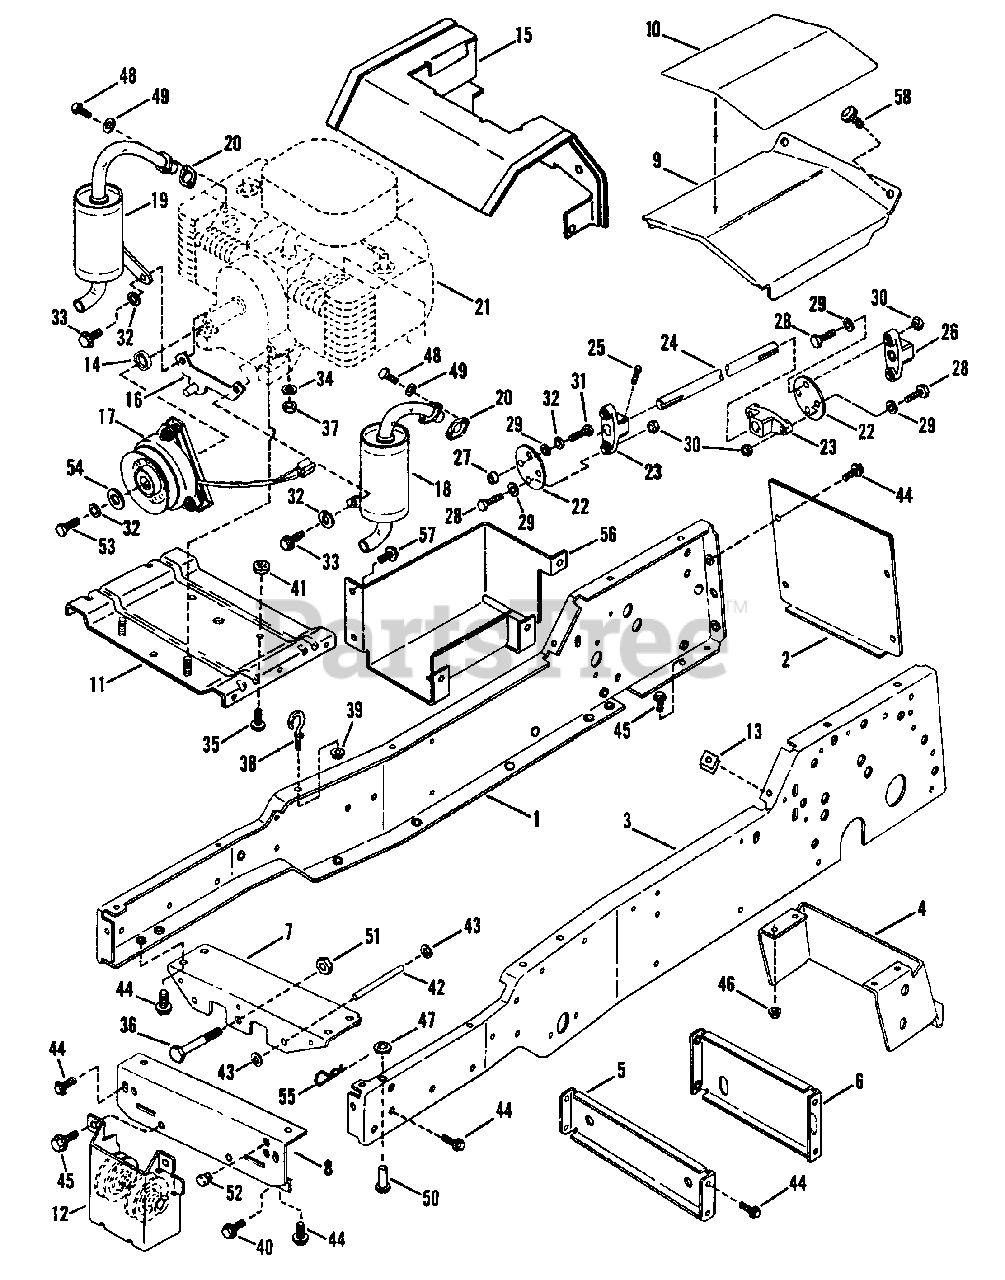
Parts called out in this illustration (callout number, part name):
1	CHANNEL, Right Hand Frame
2	PLATE, Rear Cover
3	CHANNEL, Left Hand Frame
4	DRAWBAR
5	BRACE, Forward
6	BRACE, Rear Cross
7	CHANNEL, Front Axle Support
8	PLATE, Front Frame
9	COVER, Console
10	DECAL, Console Cover
11	BASE, Engine
12	ASSEMBLY, Mule Drive
13	U-NUT, 1/4-20 x 3/4"
14	SPACER, 1" x 1 3/8 x .30" (PM)
15	ASSEMBLY, Heat Shield
16	BRACKET, Clutch Retainer
17	KIT, Electric Clutch
18	MUFFLER, LT 12 & LT 16 Engine - B&S
19	MUFFLER, LT 12 & LT 16 Engine - B&S
20	GASKET, Exhaust
21	ENGINE, Briggs Model 402437-1206-01, 16 HP
22	DISC, Flex Coupling
23	HUB, Flex Coupling
24	SHAFT, Drive
25	SET-SCREW, 5/16-18 x 1/2" Square Head
26	HUB, Flexible Coupling (Threaded center)
27	SPACER, Flexible Coupling
28	SCREW, 3/8-16 x 1", Hex Head Cap, Grade 2
29	WASHER, 3/8" Flat
30	NUT, 3/8-16 Hex Center Lock, Grade B or 5
31	SCREW, 3/8-16 x 1-1/4" Hex Head Cap, Grade 5
32	WASHER, 3/8 Split Lock
33	SCREW, 3/8-16 x 7/8", Hex Head Cap, Grade 5
34	WASHER, 5/16 Split Lock
35	SCREW, 3/8-16 x 1" Hex Washer Self-Tap
36	SCREW, 1/2-20 x 4" Hex Head Cap, Grade 5
37	NUT, 5/16-18 Hex
38	HOOK, Hood Latch
39	NUT, 5/16-18 Hex Flange, Grade 5
40	SCREW, 1/4-20 x 5/8" Hex Washer Self-Tap
41	RETAINER, 3/8 Bolt
42	STOP, Axle
43	RETAINER, 3/8 Shaft
44	SCREW, 5/16-18 x 5/8" Hex Washer Self-Tap
45	BOLT, 3/8-16 x 3/4" HeX Flange Lock
46	NUT, 3/8-16 Hex Flange Lock
47	PUSH-NUT, 1/2
48	SCREW, 1/4-20 x 5/8" Hex Head Cap
49	WASHER, 1/4 Split Lock
50	PIN, 1/4 x 7/8" Clevis
51	NUT, 1/2-20 Hex Nyloc
52	RELIEF, Strain
53	SCREW, 3/8-24 x 1-5/8" Hex Head Cap, Grade 5
54	WASHER, .406 I.D.
55	PIN, 1/4 Hair
56	BOX, Battery
57	SCREW, 1/4-20 x 3/8" Hex Washer Self-Tap
58	KNOB, 1/4-20 x 3/4"
